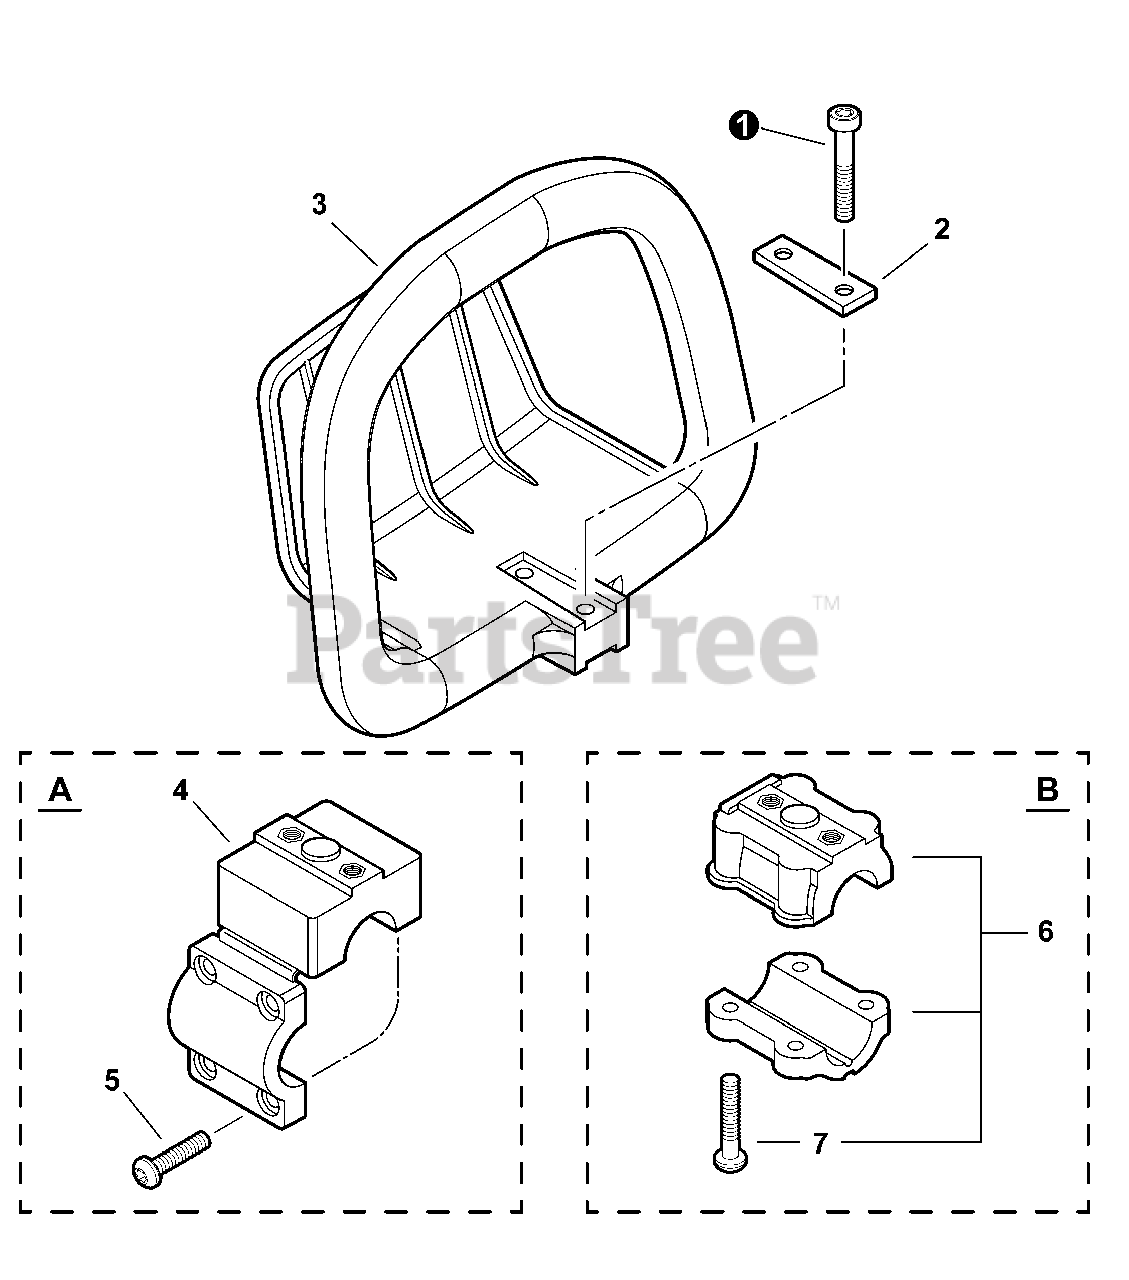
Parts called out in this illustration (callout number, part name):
1	SCREW - 5×30
2	PLATE, EYE
3	HANDLE - FRONT
4	BRACKET, HANDLE
5	SCREW - 5×20
6	BRACKET KIT
7	SCREW - 5×25
